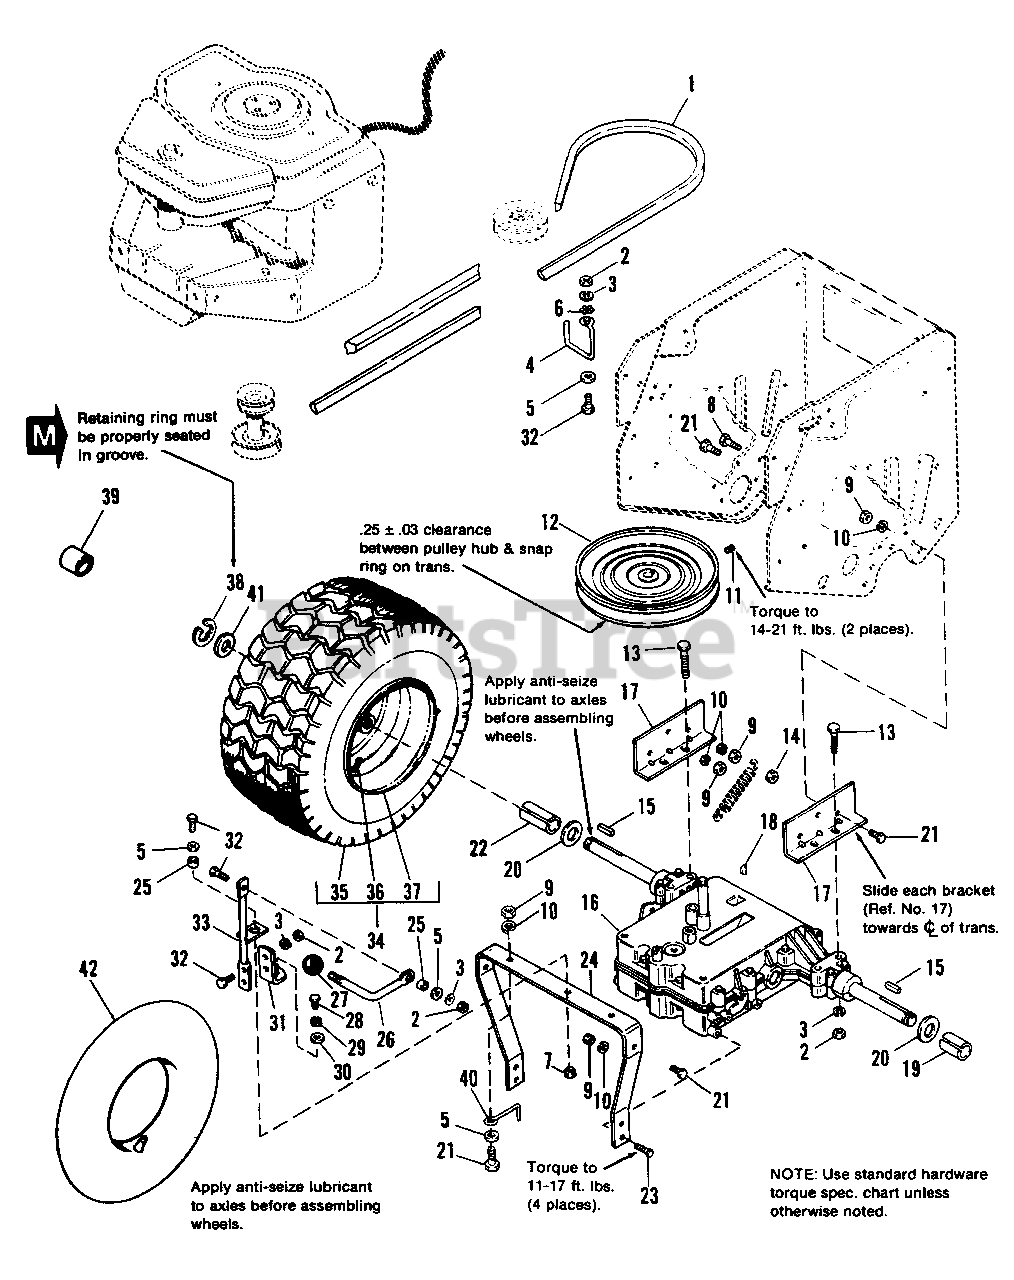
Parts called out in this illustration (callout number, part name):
1	V-BELT, Transmission Drive
2	NUT, Hex, Full, 5/16-18
3	LOCKWASHER, 5/16
5	WASHER, Plain, 5/16
6	LOCKWASHER, Ext. Tooth
7	NUT, Hex, Lock, 5/16-18
8	CAPSCREW, Hex Hd., 3/8-16 x 1-1/2
9	NUT, Hex, Full, 3/8-16
10	LOCKWASHER, 3/8
11	SETSCREW, 5/16-18 x 5/8
12	PULLEY ASSY., Transmission
13	CAPSCREW. Hex Hd., 5/16-18 x 2-1/2
14	LOCKNUT, Hex, 3/8-16
15	KEY, 3/16 x 3/16 x 1-1/2
16	TRANSAXLE, 5 Speed
17	SUPPORT, Transmission, Rear
18	KEY, Woodruff, #9
20	WASHER
21	CAPSCREW, Hex Hd., 3/8-16 x 1
23	SCREW, Hex, Taptite, 5/16-18 x 5/8
24	SUPPORT. Transmission, Front
27	KNOB, Shift
28	CAPSCREW, Hex Hd., 1/4-28 x 5/8
29	LOCKWASHER, 1/4
30	WASHER, Plain, 3/16
31	LINK, Shift, Lower
32	CAPSCREW, Hex Hd., 5/16-18 x 1
33	SHIFT LINK ASSY., Upper
34	WHEEL & TIRE ASSY.
35	TIRE, 20 x 10-10
36	VALVE STEM & CAP
39	HUB CAP, Threaded
42	TUBE, 20 x 8-10
